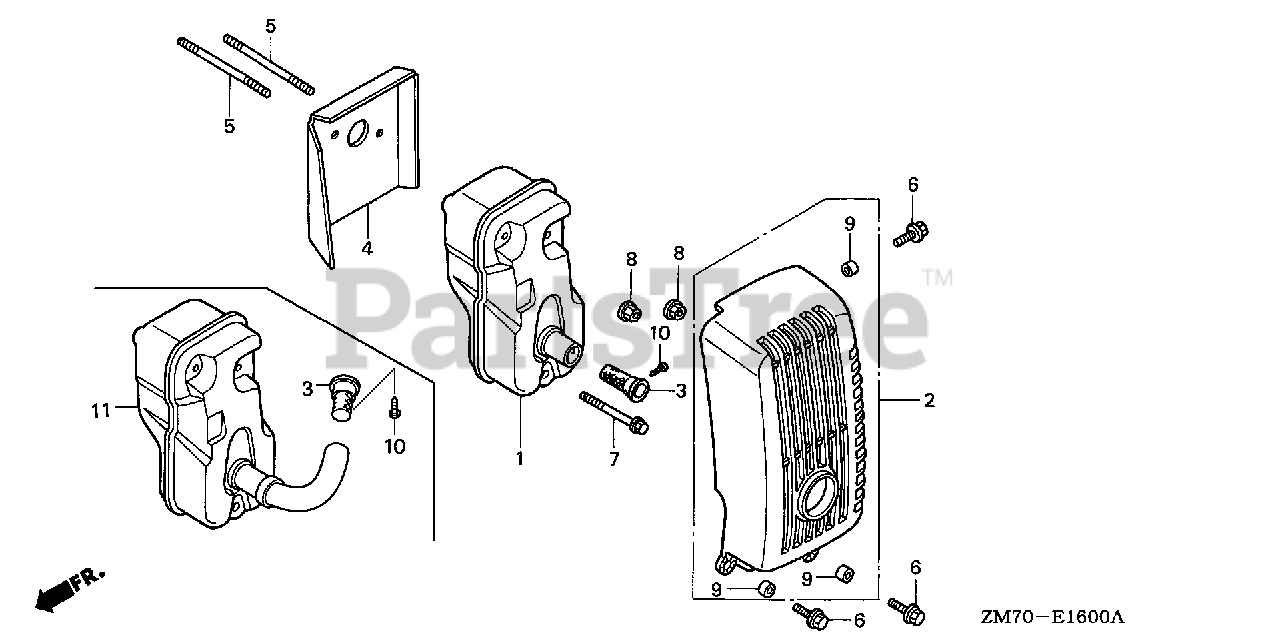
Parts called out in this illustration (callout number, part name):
1	MUFFLER
3	ARRESTER, SPARK
4	GUIDE, AIR
5	BOLT, STUD (5X55)
7	BOLT, FLANGE (5X35)
8	NUT, SELF-LOCK (5MM)
10	SCREW, TAPPING (4X8)
